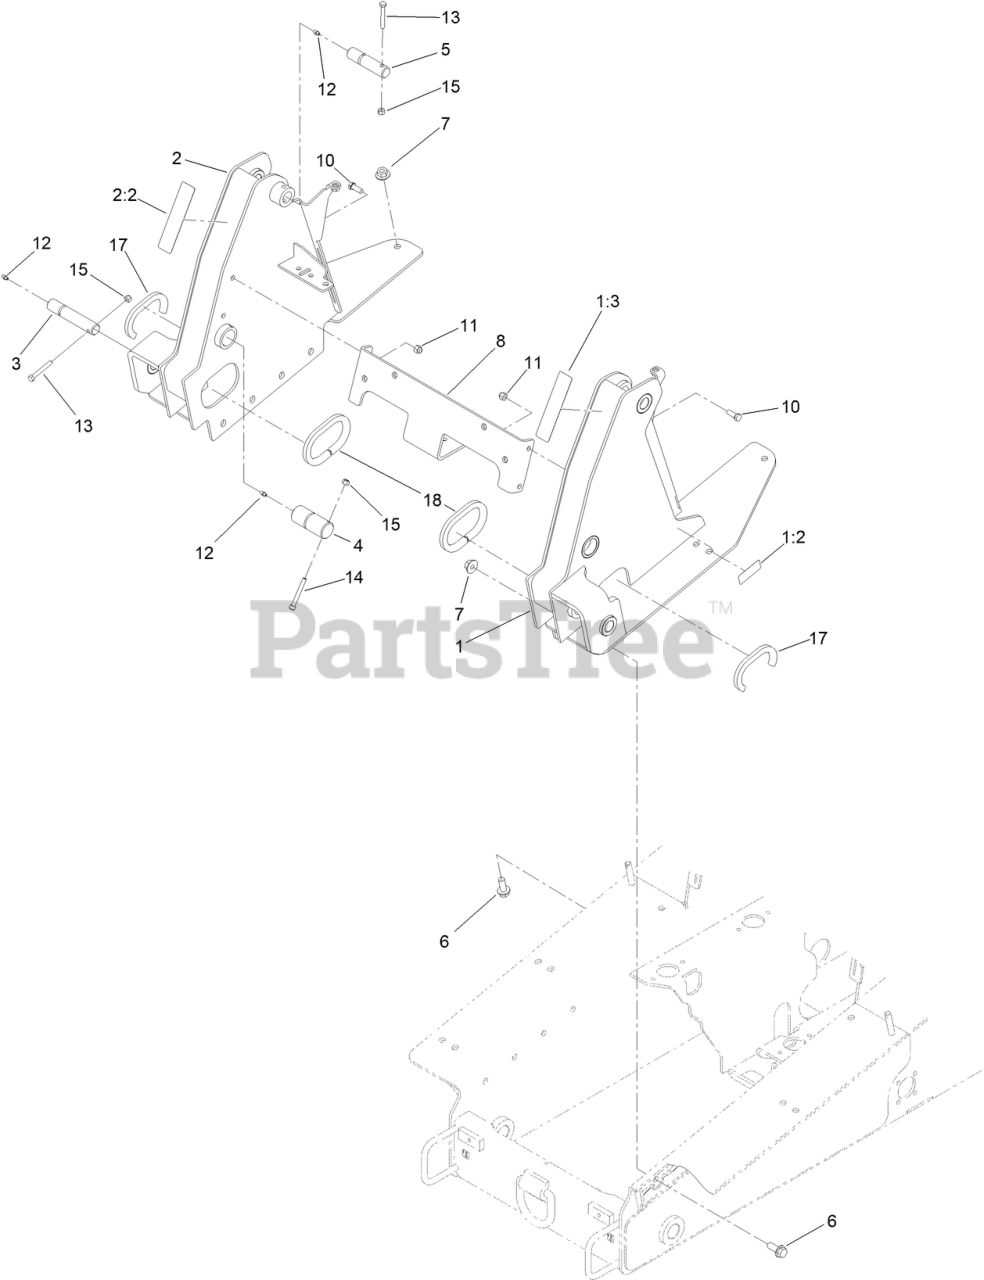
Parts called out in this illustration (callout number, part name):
1	TOWER-FRONT, LH
1:2	DECAL-SURFACE, HOT
1:3	TAPE-REFLECTIVE
2	TOWER-LOADER, RH ASM
2:2	TAPE-REFLECTIVE
3	PIN-HYD
4	PIN-ARM
5	PIN-LINK
6	SCREW-HHF
7	NUT-LOCK, FLANGE
8	PLATE-CROSS, TOWER
10	SCREW-HH
11	NUT-LOCK, NI
12	FITTING-GREASE
13	SCREW-HH
14	SCREW-HSH
15	NUT-LOCK, NI
17	TRIM-SEAL
18	TRIM-SEAL
